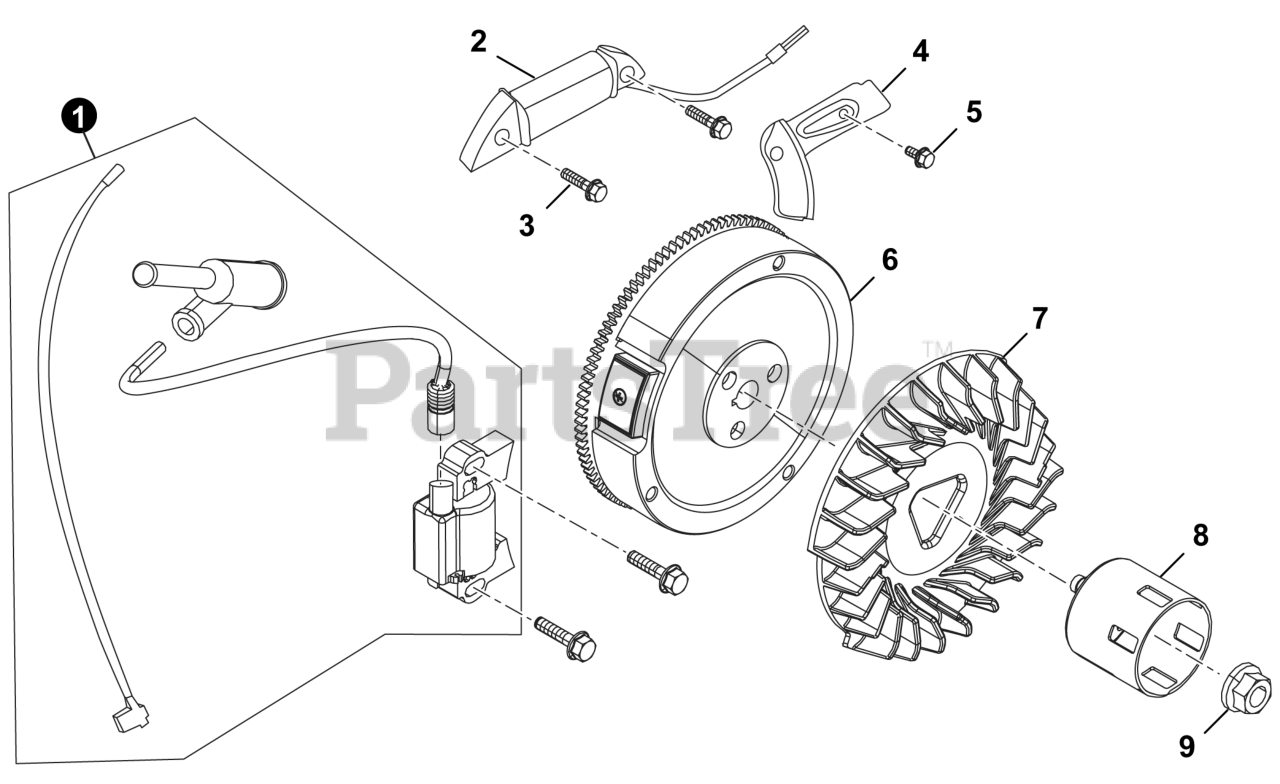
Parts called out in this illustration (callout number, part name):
1	COIL, IGNITION
2	COIL, CHARGE
4	CLAMP, CHARGE COIL
6	FLYWHEEL
7	IMPELLER
8	PULLEY,STARTER
9	NUT, FLYWHEEL
